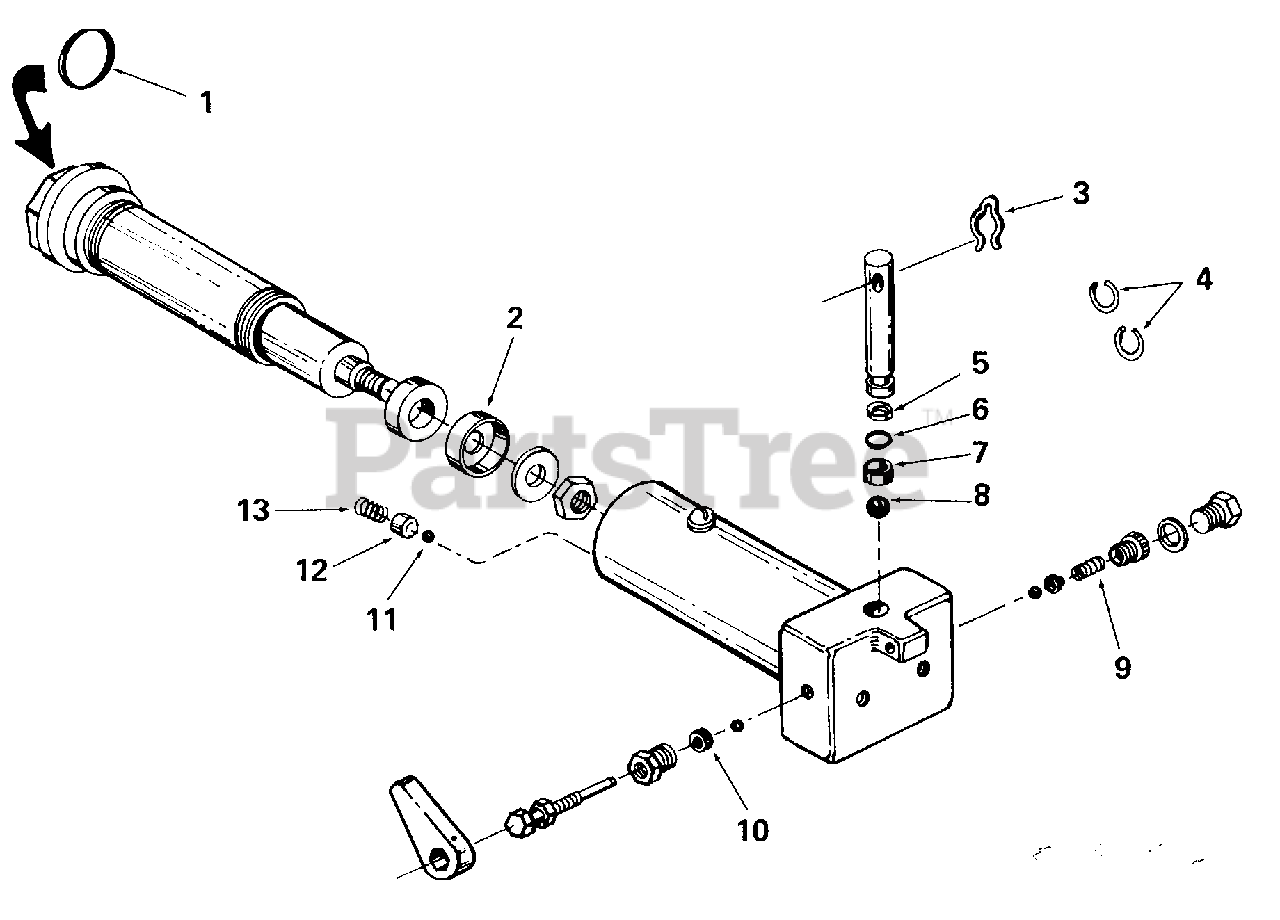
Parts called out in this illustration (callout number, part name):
1	Quad Ring
2	Cup
3	Hair Pin Clip
4	Pin Ring
5	Back-Up Washer
6	"O"-Ring
7	Ball Retainer
8	Ball
9	Spring
10	Packing
11	Ball
12	Ball Retainer
13	Spring
